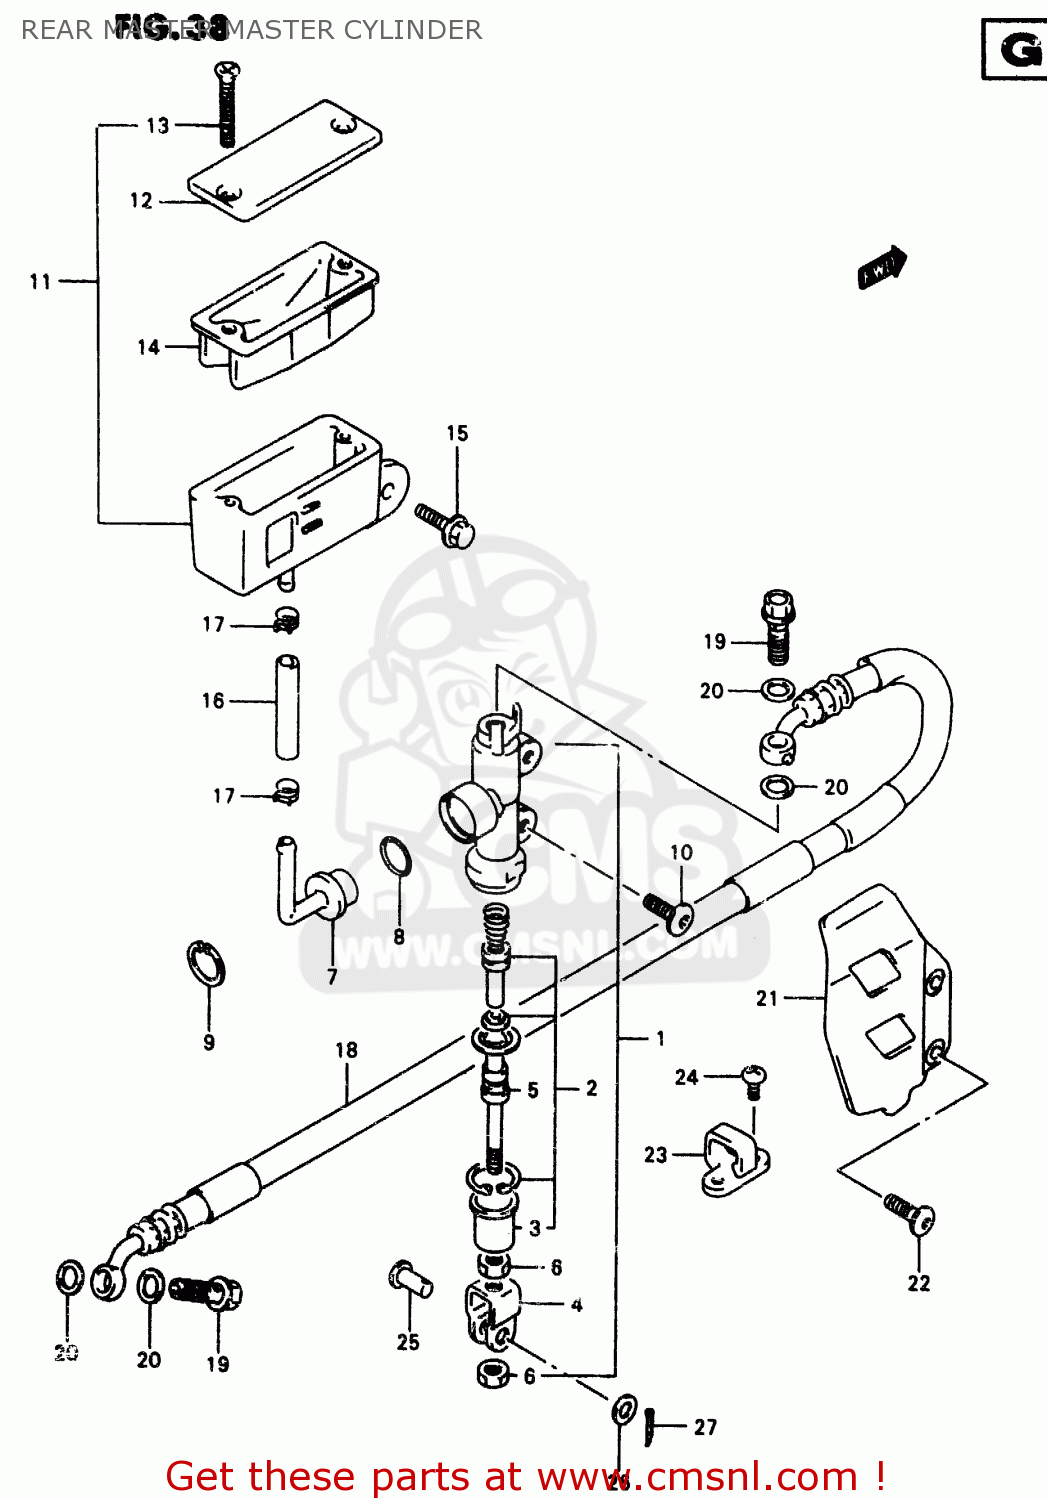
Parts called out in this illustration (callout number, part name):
1	CYLINDER ASSY,RR MASTER
2	PISTON/CUP SET
3	BOOT
4	YOKE
5	ROD,PUSH
6	NUT
7	CONNECTOR
8	O RING
9	CIRCLIP
10	SCREW(6X16)
11	TANK ASSY,RESERVOIR
12	CAP
13	SCREW
14	DIAPHRAGM
15	BOLT
16	HOSE,RESERVOIR TANK
17	CLAMP,RESERVOIR HOSE
18	HOSE COMP,REAR BRAKE
19	BOLT UNION
20	WASHER(10X15X1.5)
21	GUARD,RR MASTER CYLINDER
22	SCREW(6X16)
23	GUIDE,RR BRAKE
24	SCREW
25	PIN(8X20)
26	WASHER(8.5X13X1.6)
27	PIN
